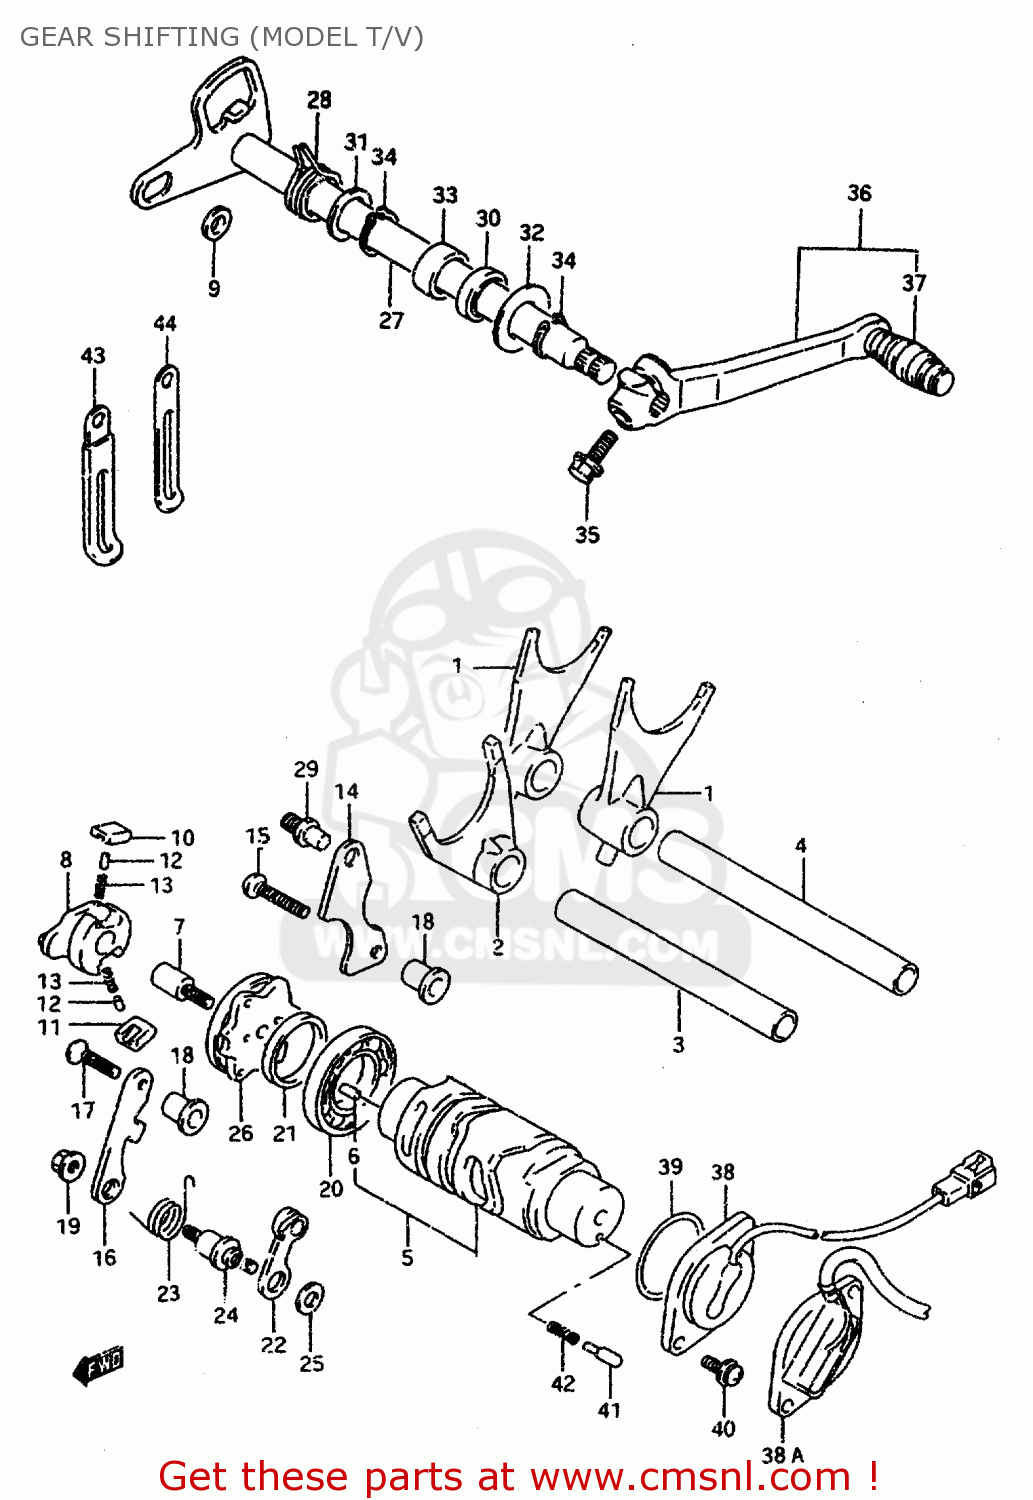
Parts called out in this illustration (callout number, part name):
1	FORK,GEAR SHIFT NO.1
2	FORK,GEAR SHIFT NO.3
3	SHAFT,GEAR SHIFT FORK
4	SHAFT,GEAR SHIFT FORK(L:128)
5	CAM,GEAR SHIFT
6	PIN
7	PIN,SHIFT CAM DRIVEN GEAR
8	SHIFTER,GEAR SHIFT CAM
9	SPACER(7X10X5)
10	PAWL,GEAR SHIFT NO.1
11	PAWL,GEAR SHIFT NO.2
12	PIN(5X8)
13	SPRING
14	LIFTER,GEAR SHIFT PAWL
15	SCREW 6X30
16	GUIDE,GEAR SHIFT CAM
17	SCREW
18	SPACER(6.1X10X16)
19	NUT
20	BEARING(25X47X8)
21	WASHER(25X32X3)
22	STOPPER,GEAR SHIFT CAM
23	SPRING,STOPPER ARM
24	SUPPORT,CAM STOPPER ARM
25	WASHER
26	PLATE,GEAR SHIFT CAM
27	SHAFT COMP,GEAR SHIFTING
28	SPRING
29	STOPPER,GEAR SHIFT CAM
30	SEAL,OIL(14X22X6)
31	WASHER,THRUST
32	WASHER(14X29X0.8)
33	BEARING(14X20X12)
34	CIRCLIP
35	BOLT
36	LEVER ASSY,GEAR SHIFT
37	RUBBER,GEAR SHIFT PEDAL
38	TERMINAL BASE ASSY,NEUTRAL
38A	BASE ASSY,GEAR SHIFT TERMINAL
39	O RING(D:2.4,ID:35.5)
40	SCREW
41	PIN(5X15.5)
42	SPRING
43	CLAMP(L:45)
44	CLAMP
